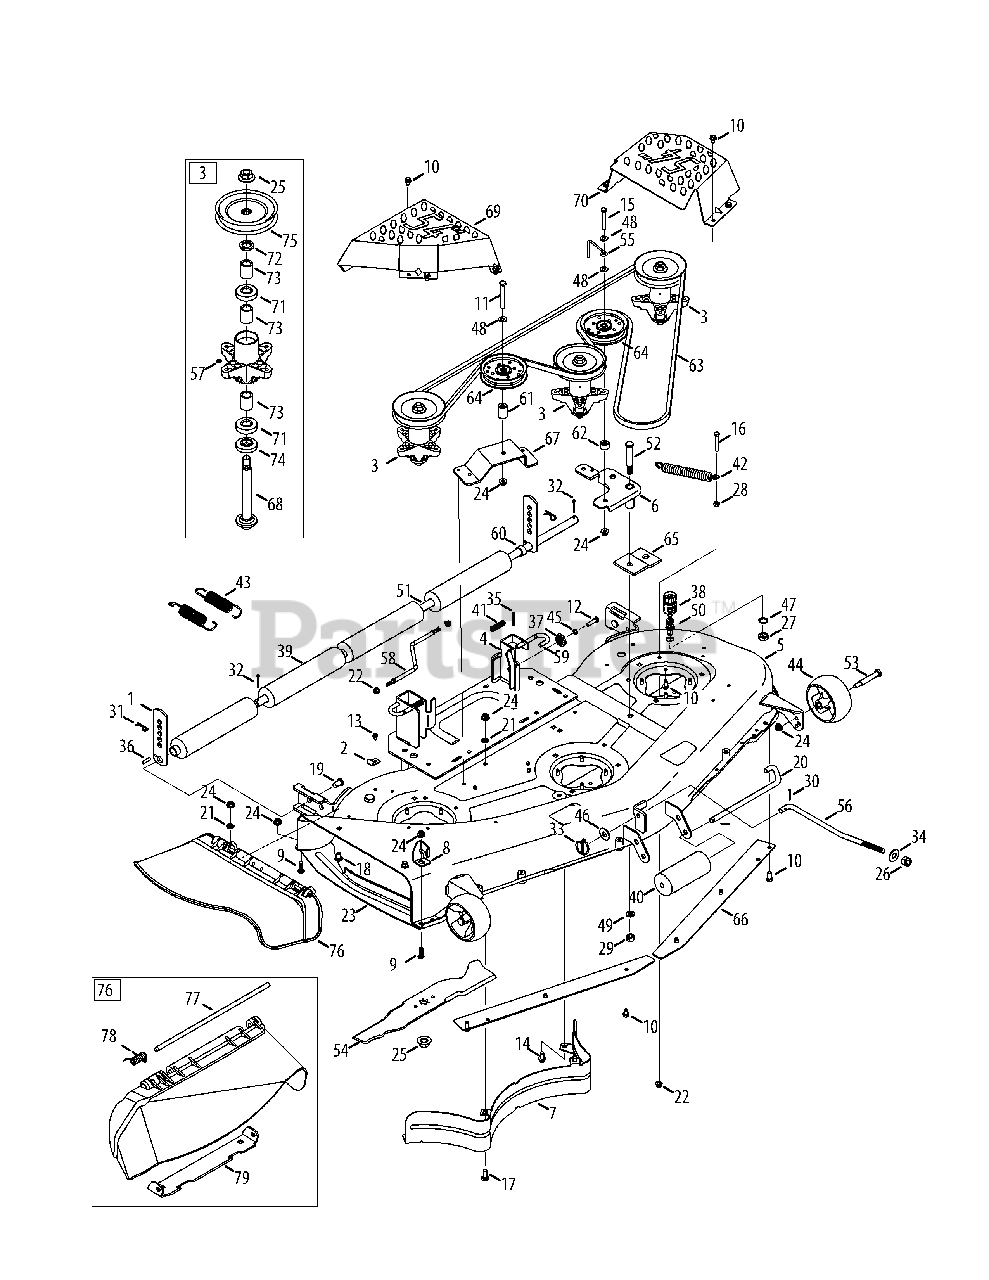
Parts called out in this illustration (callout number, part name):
1	Height Adjust Bracket
2	Retainer Hook Bracket
3	Spindle Assembly
4	Deck Hanger Bracket Assembly
5	Deck Assembly
6	Idler Assembly
7	Inner Baffle
8	Deflector Chute Stop
9	Hex Screw, 3/8-16 x 1.00
10	Taptite Screw, 5/16-18 x .750
11	Hex Screw, 3/8-16 x 3.00
12	Hex Screw, 5/16-18 x 1.25
13	Hex Screw, 1/4-20 x .500
14	Taptite Screw, 3/8-16 x 0.750
15	Hex Screw, 3/8-16 x 2.50
16	Hex Screw, 5/16-18 x 2.00
17	Carriage Bolt, 3/8-16 x 1.00
18	Carriage Bolt, 3/8-16 x 0.75
19	Clevis Pin, .50 DIA x .78 LG
20	Roller Pin, 1/2 DIA x 7.31 LG
21	Push Nut, 3/8
22	Flangelock Nut, 5/16-18
23	Finger Guard
24	Flangelock Nut, 3/8-16
25	Flange Nut, 5/8-18
26	Flexlock Nut, 1/2-13
27	Hex Nut, M16-1.5 DIN 936
28	Hex Nut, 5/16-18
29	Hexlock Nut, Counterlock, 1/2-13
30	Cotter Pin, 3/32 x 1.0
31	Click Pin, .092 x 1.64 LG
32	Cotter Pin, 5/32 x 1.25
33	Lynch Pin, .1875
34	Washer, .630 x 1.25 x .180
35	Cotter Pin, 1/8 x 1.25
36	Spring Pin, 1/4 DIA x 1.00 LG
38	Water Nozzle Adaptor
39	Deck Roller
40	Front Roller
41	Compression Spring, .535 OD x 1.751 LG
42	Extension Spring, .85 OD x 5.915 LG
43	Extension Spring, 1.15 OD x 5.99 LG
44	Deck Wheel
45	Lock Washer, 5/16
46	Flat Washer, .531 x 1.25 x .100
47	Lock Washer, 5/8
48	Flat Washer, .406 x .875 x .059
49	Lock Washer, 1/2
50	Deck Water Nozzle
51	Shaft, .750 x .47.12
52	Shield Screw, .625 x 2.50:1/2-13
53	Shoulder Bolt, .496 x 2.50:3/8-16
55	Belt Keeper Rod
56	Deck Lift Rod
57	Lube Fitting
58	Deck Sway Rod
59	Deck Release Handle Rod
60	Spacer, .82 ID x 1.00 OD x .53
61	Spacer, .380 x .900 x 1.313
62	Spacer, .385 ID x .88 x .64
64	Idler Pulley, 4.25"DIA
65	Pulley Stabilizer Bracket
67	Stationary Idler Bracket
68	Spindle Shaft, 6.95 LG
69	RH Spindle Cover
70	LH Spindle Cover
71	Ball Bearing, .787 ID x 1.85 OD x .551
72	Spacer, .790 ID x 1.25 OD x .175
73	Spacer, .80 x 1.10 x 1.322 LG
74	Spacer, .79 x 1.82 x .55 LG
75	Deck Pulley
76	Chute Assembly
78	Torsion Spring, .44 ID x 2.0
79	Chute Bracket
